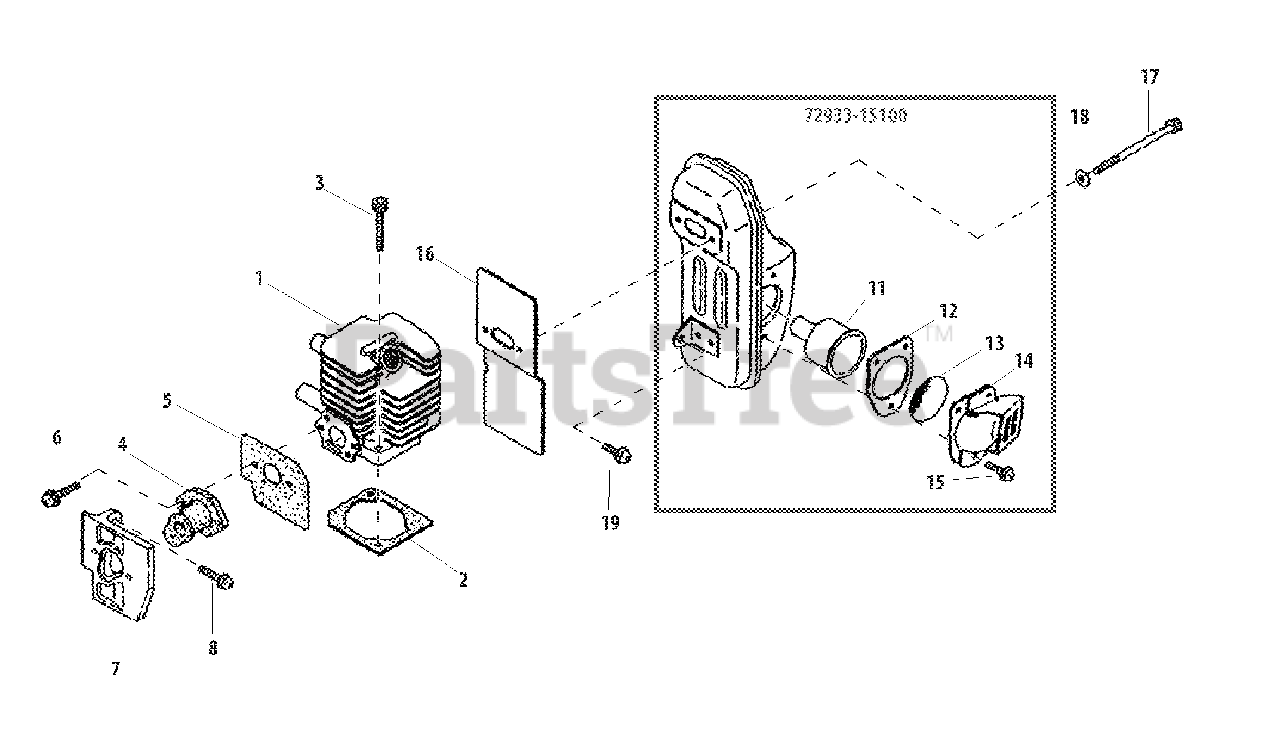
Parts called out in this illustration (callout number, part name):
1	CYLINDER
2	GASKET, CYLINDER
3	BOLT 5×20
4	BELLOWS, INTAKE
5	GASKET, INTAKE
6	SCREW
7	INSULATOR, INTAKE
8	SCREW
11	GUIDE, EXHAUST
12	GASKET, EXHAUST
13	SCREEN, SPARK ARRESTER
14	GUIDE, EXHAUST
16	HEAT SHIELD, EXHAUST
17	BOLT 5×55
18	WASHER, FLAT 5.5×10×0.8
19	SCREW
72933-15100	MUFFLER ASSY
